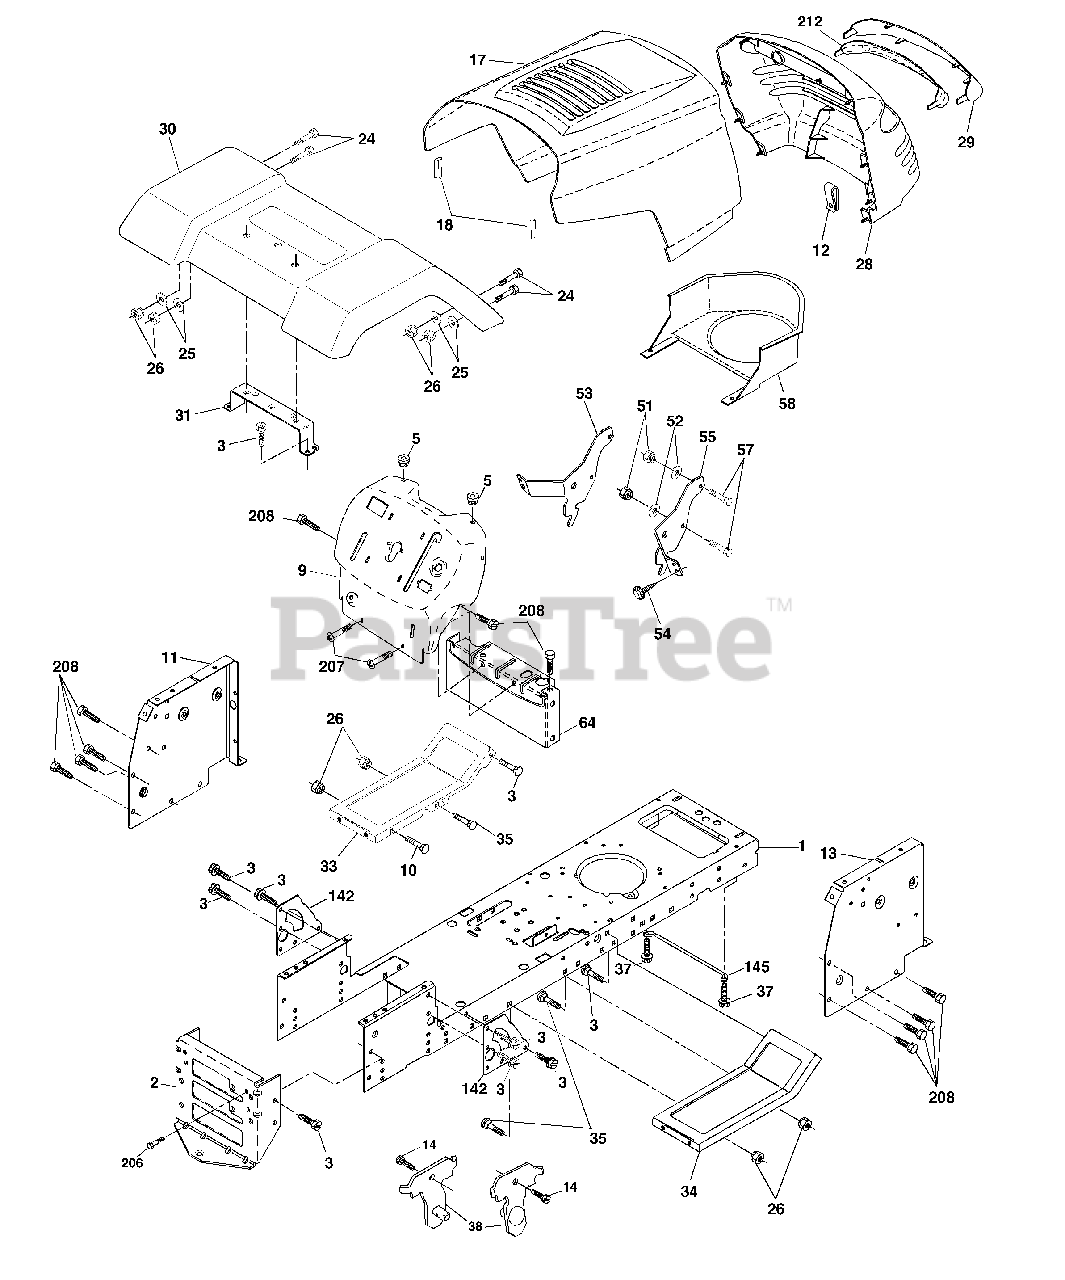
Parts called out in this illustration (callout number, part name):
1	Chassis
2	Drawbar
3	Screw 3/8-16 x 3/4
5	Bumper Hood/Dash
10	Bolt Rd Hd Sqnk. 3/8-16 Unc x 1
11	Panel Asm. Dash Lh
12	Clip Tinnerman Grile P/L
13	Panel Dash Rh
14	Screw Thdrol 3/8-16 x 1/2
17	Hood
18	Bumper Hood
24	Bolt Fin Hex 3/8-16 Unc x 1 Gr. 5
25	Washer 13/32 x 13/16 x 12 Ga.
26	Nut Lock Hex w/Insert 3/8-16 UNC
28	Grill/Lens Asm
29	Lens Grille Private label
30	Fender Asm
31	Bracket Fender
33	Footrest LH
34	Footrest RH
35	Bolt Rd Hd Sht. Sqnk. 3/8-16 x 3/4
37	Screw Thdrol 5/16-18 x 1/2 Tyt
38	Bracket Asm. Pivot Mower Rear
51	Nut Lock Hex W/Ins. 1/4-20
52	Washer 9/32 x 7/8 x 16 Ga.
53	Bracket Grille LH
54	Screw Hex Wshd 8-18 x 7/8
55	Bracket, Grille RH
57	Bolt Fin Hex 1/4-20 x .75
58	Air Duct Private Label
64	Dash Lower
142	Plate Reinforcement
145	Rod Pivot Chassis/Hood
206	Bolt shoulder 5/16-18
207	Screw Thdrol 5/16-18 x 1/2
208	Screw Thdrol 3/8-16 x 1/2
212	Insert Lens Reflector
